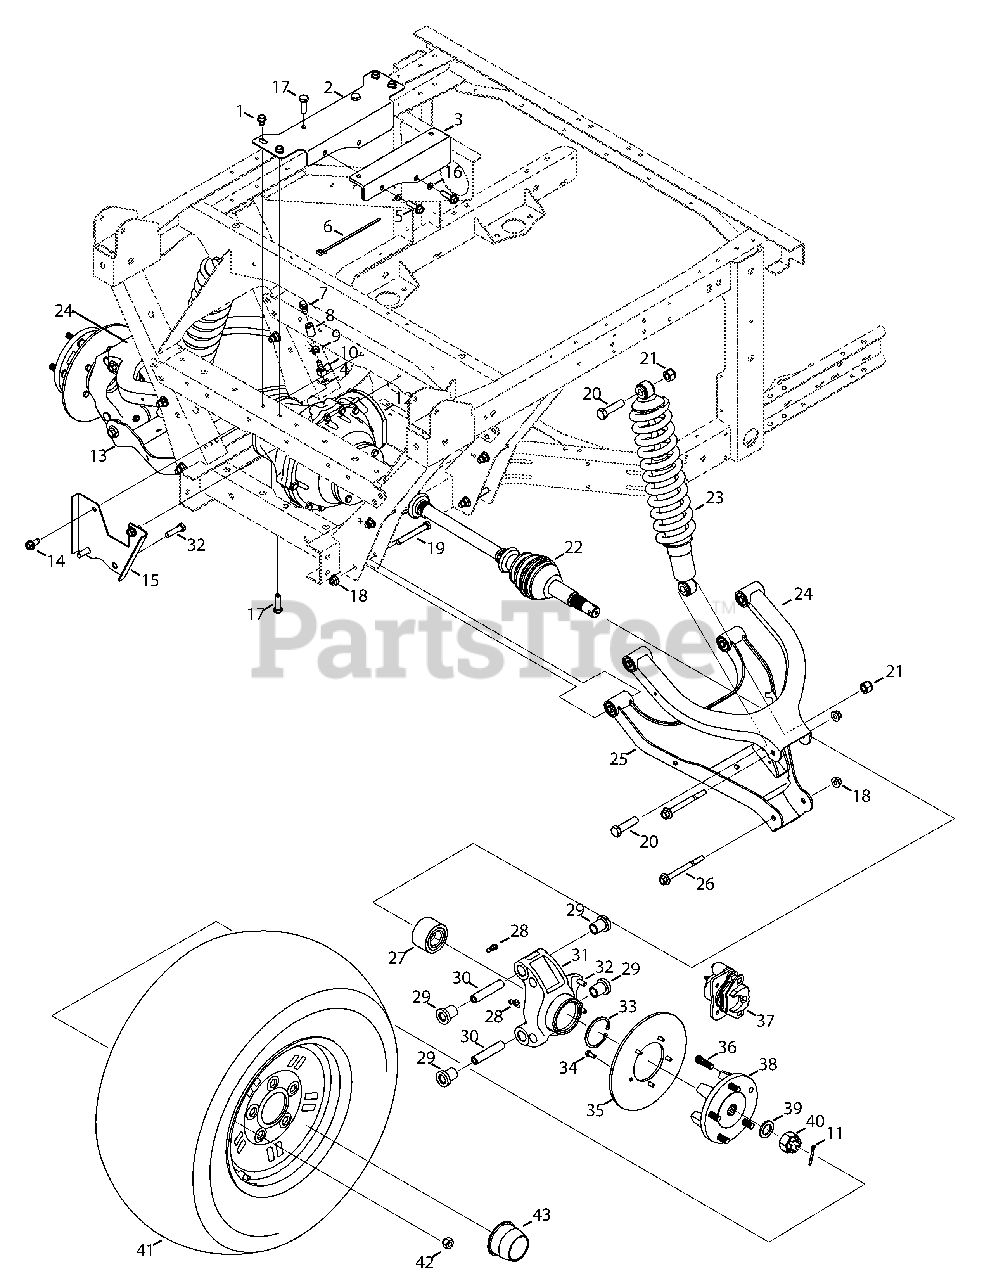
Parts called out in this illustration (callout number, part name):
1	Screw, tt, 5/16-18 x 0.500
2	Bracket, rear/diff, 4x4
3	Spacer, Differential
4	Nut, Jam, M12 x 1.5 x 6MM
5	Screw, 3/8-16 x 2.25, gr5, std
6	Tie, Cable
7	Vent, 3/8 Dia.
8	Hose, fuel Line
9	Clamp, hose, .540 Dia.
10	Fitting, Fuel Pickup
11	Pin, cotter, 5/32, 1.25
12	Differential Assembly, complete
13	Control Assembly, lwr, l/rr
14	Screw, tt, 3/8-16 x .750
15	Bracket, Diff, rr
16	Washer, Flat, .385 x .870 x .092
17	Screw, 3/8-16 x .875, gr5, std
18	Nut, Flange Lock, 3/8-16, Nylon
19	Screw, 3/8-16 x 3.00, gr8, std
20	Screw, 1/2-13 x 2.00, gr5, std
21	Nut, Hex Lock, 1/2-13, Nylon
22	Axle Assembly, cv Joint
23	Shabs, 5.0 Stroke, rr
24	Control Assembly, rr Upr
25	Control Assembly, lwr, r/rr
26	Screw, 3/8-16 x 4.00, gr5
27	Bearing, dble Row, 60x30x37
28	Fitting, Grease
29	Bearing, Flange, .625 x .750 x .750
30	Tube, pivot, rr/cont Arm
31	Housing, rr, mach
32	Screw, m8-1.25, 25.00
33	Ring, retainer, dho-60
34	Screw, 1/4-20 x .625, gr5, lock
35	Disc, brake, 8.00x.188
36	Stud, rib Neck, 7/16-14 x 1.6
37	Brake, hydraulic, caliper, frt, RH
37	Brake, hydraulic, caliper, frt, LH
38	Hub, wheel
39	Washer, flat, .88 x 1.38 x .125, ht
40	Nut, slotted, 22x1.5
41	Wheel Assembly, RH, 25 x 11-12
41	Wheel Assembly, RH,25 x 11-12,blk
41	Wheel Assembly, RH 26 x 11-12
41	Wheel Assembly, LH, 25 x 11-12
41	Wheel Assembly, LH, 25 x 11-12, blk
41	Wheel Assembly, LH, 26 x 11-12
41	Wheel Assembly, complete, 25x10-12
41	Tire Only, 25x11-12
41	Tire Only, 25x10.5-12
41	Tire Only, 26x11-12
42	Nut, lug, 7/16-14
42	Nut, lug, 7/16-14, Chrome
43	Cap, Wheel UV
43	Cap, Wheel UV, Chrome
